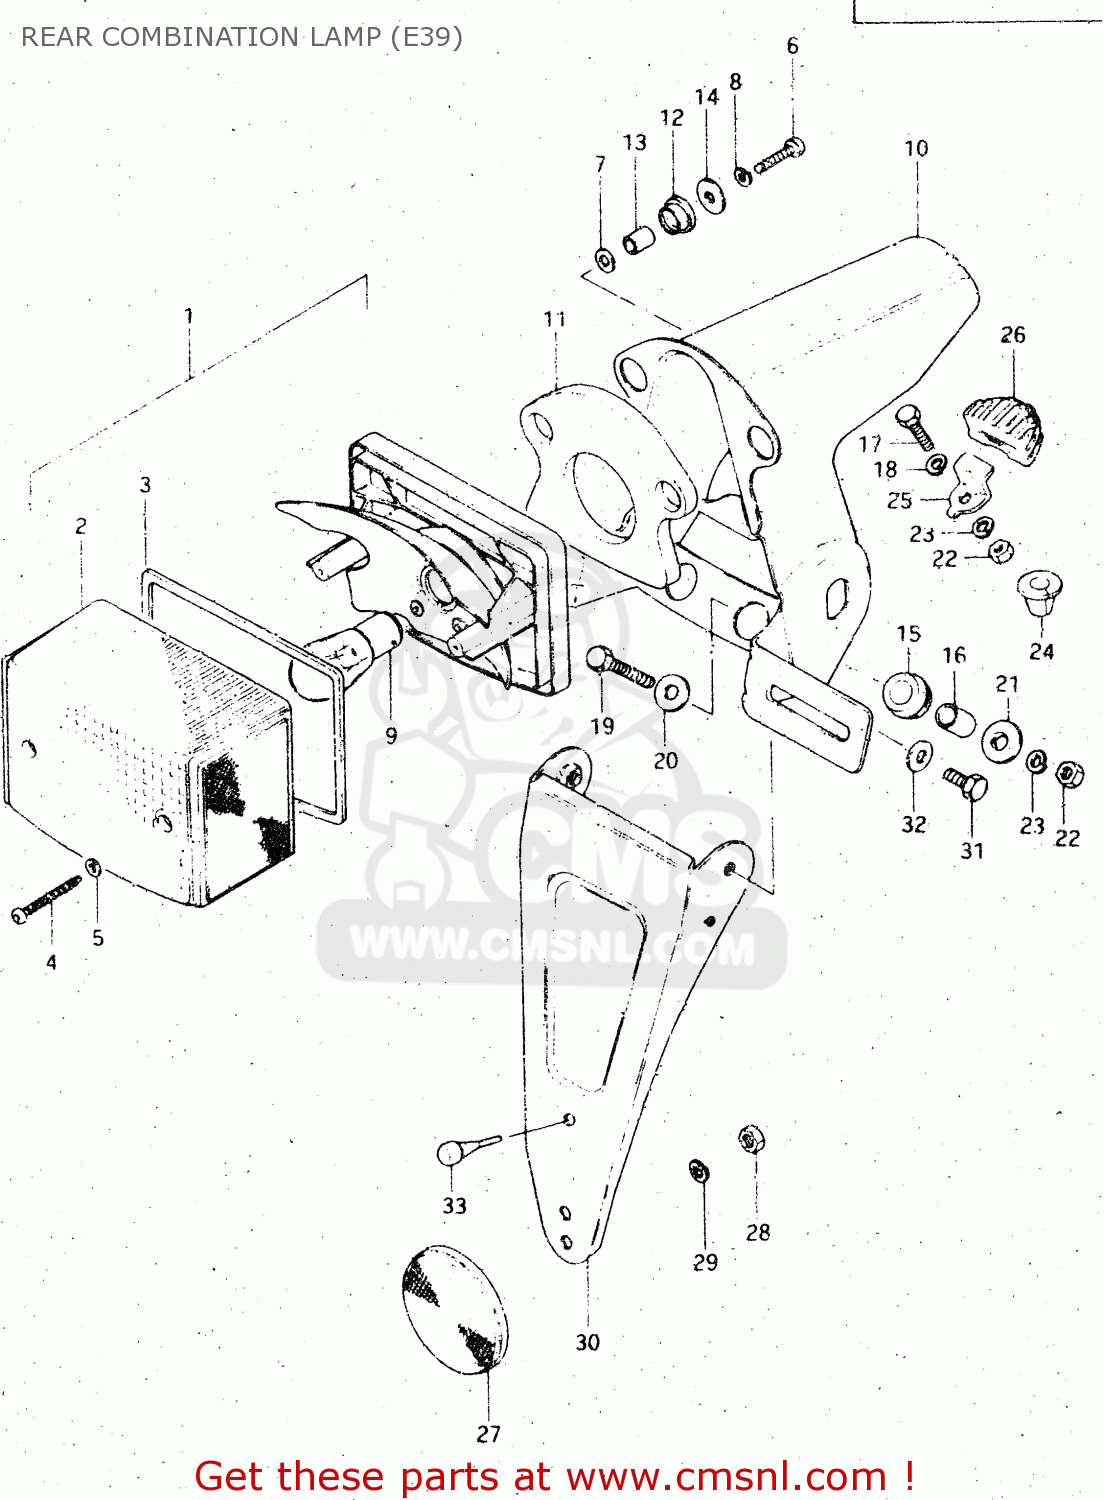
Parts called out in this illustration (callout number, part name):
1	LAMP UNIT, TAIL
2	LENS
3	GASKET (NAS)
4	SCREW
5	GASKET (NAS)
6	SCREW
7	WASHER
8	LOCK WASHER
9	BULB (6V,21/5W)
10	BRACKET ASSY
11	CUSHION,REAR COMBINATION LAMP
12	CUSHION,REAR COMBINATION LAMP
13	SPACER,REAR COMBINATION LAMP
14	WASHER,REAR COMBINATION LAMP
15	CUSHION,REAR COMBINATION LAMP
16	SPACER
17	BOLT
18	LOCK WASHER
19	BOLT
20	WASHER (6.5X20X1.2)
21	WASHER
22	NUT
23	WASHER, LOWER
24	GROMMET
25	PLATE
26	CUSHION
27	REFLEX REFLECTOR,RR
28	NUT
29	LOCK WASHER
30	BRACKET
31	BOLT
32	WASHER
33	CUSHION
